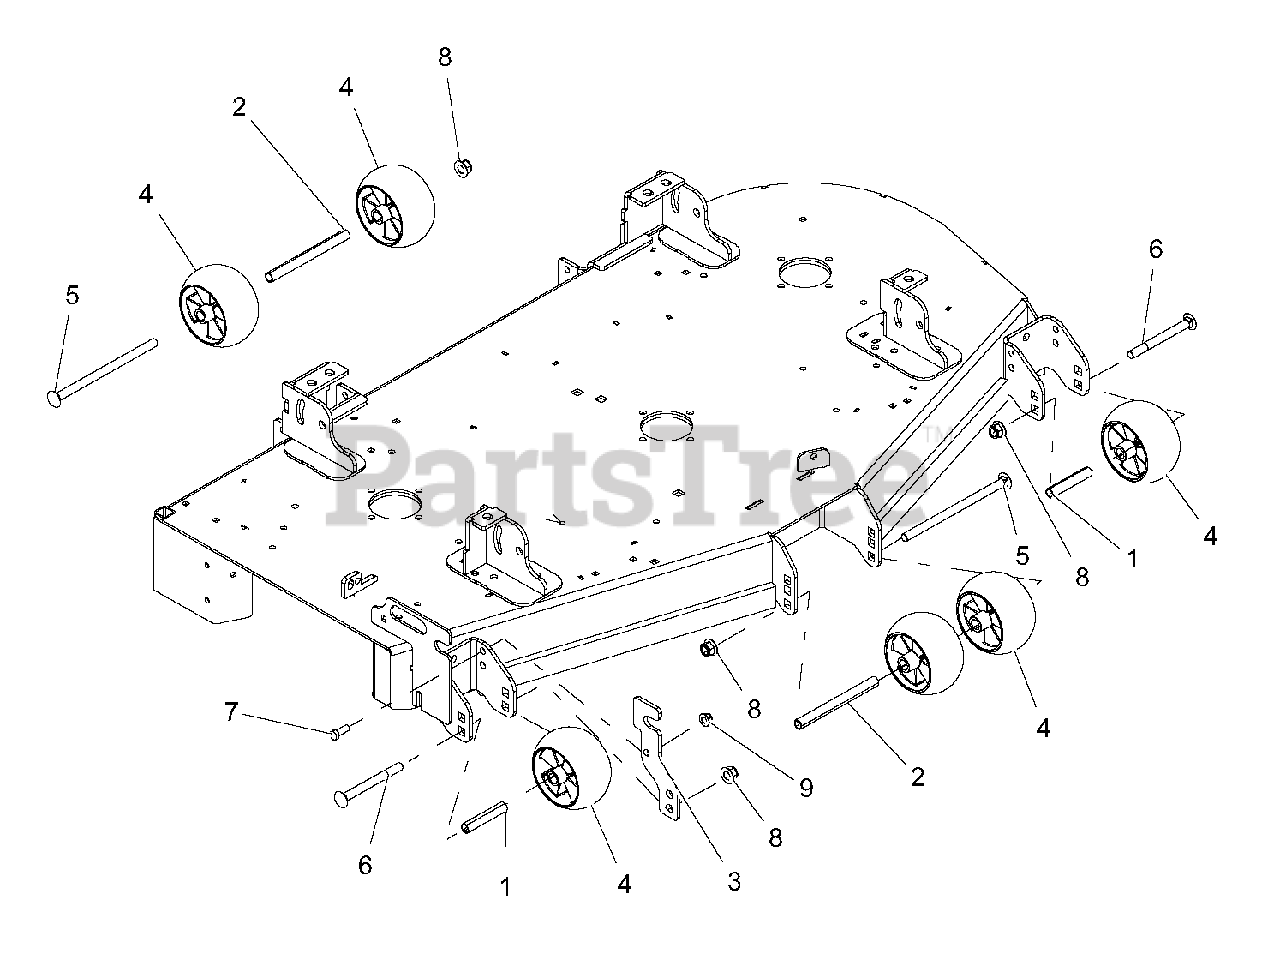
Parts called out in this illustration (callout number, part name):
1	SPACER, .510X.625X3.35
2	SPACER, .510X.625X6.70
3	CHUTE STORAGE BRACKET-RED
4	ANTI-SCALP WHEEL - 5X3 CTR
5	BLT-RDHDSQNK .50-13X8.50 Y
6	BLT-RDHDSQNK .50-13X5.00 G5
7	BLT-HEX .38-16X1.00 GR5 YWZC
8	NUT-LK-NYL-FLG .50-13 YWZC
9	NUT-LK-NYL-FLG .38-16 YWZC
